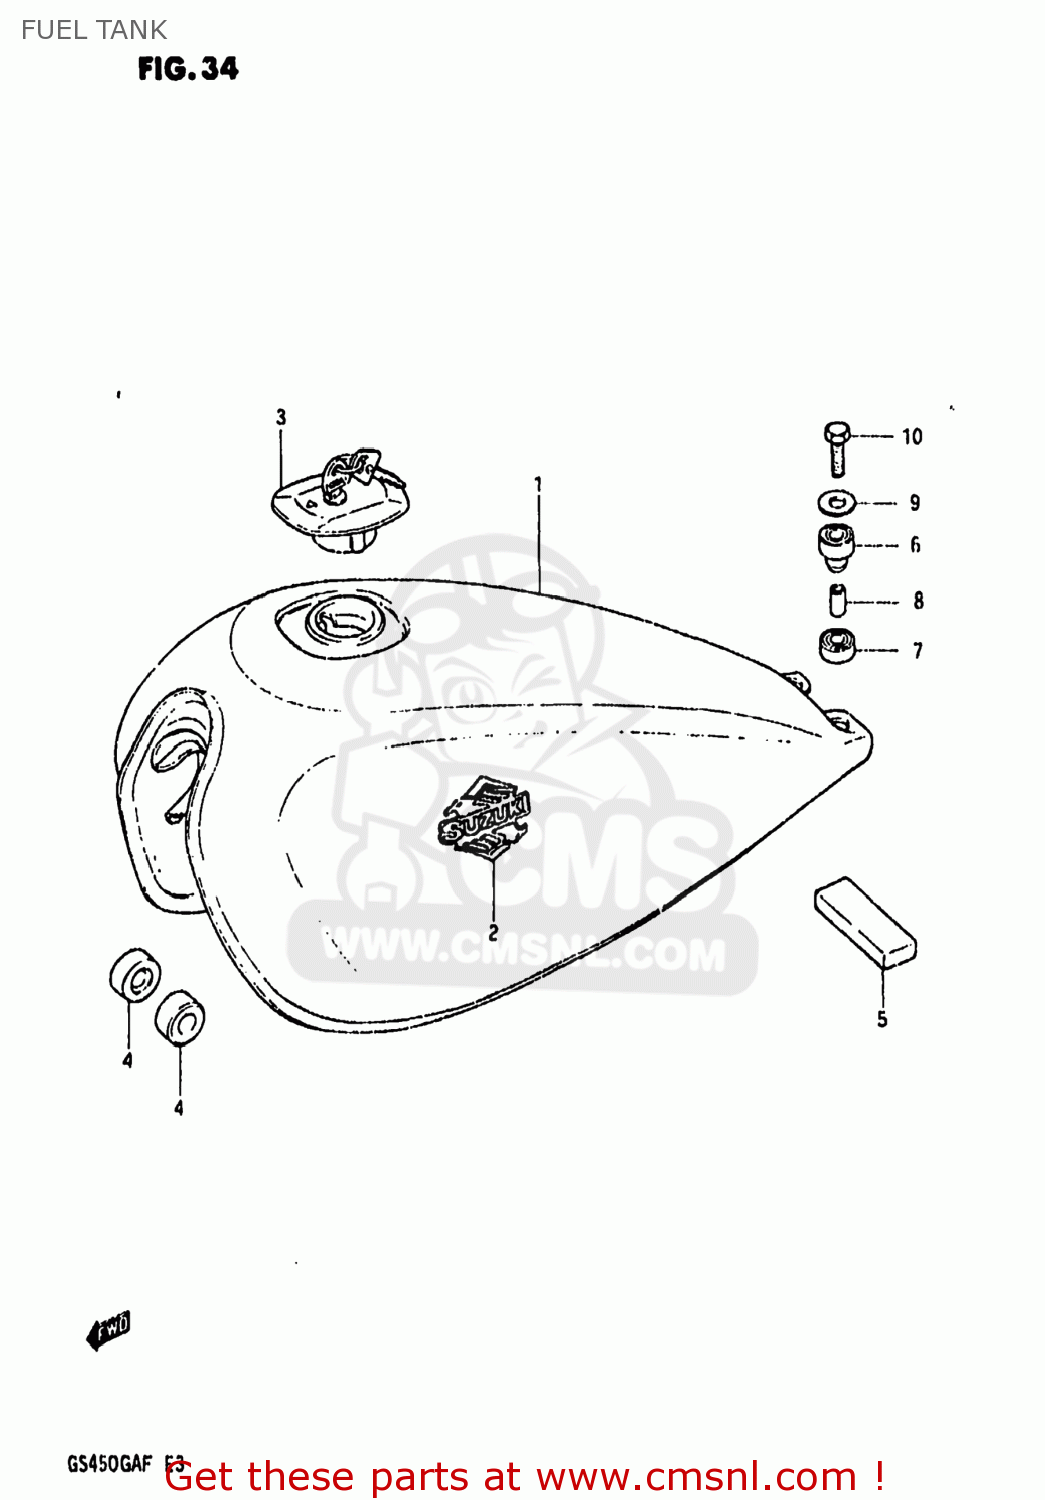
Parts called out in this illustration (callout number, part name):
1	TANK ASSEMBLY,FUEL
2	EMBLEM,FUEL TANK
3	CAP ASSEMBLY,FUEL TANK
4	CUSHION
5	CUSHION
6	CUSHION
7	CUSHION
8	SPACER (6.4X9X20)
9	WASHER (6.5X24X1.6)
10	BOLT
